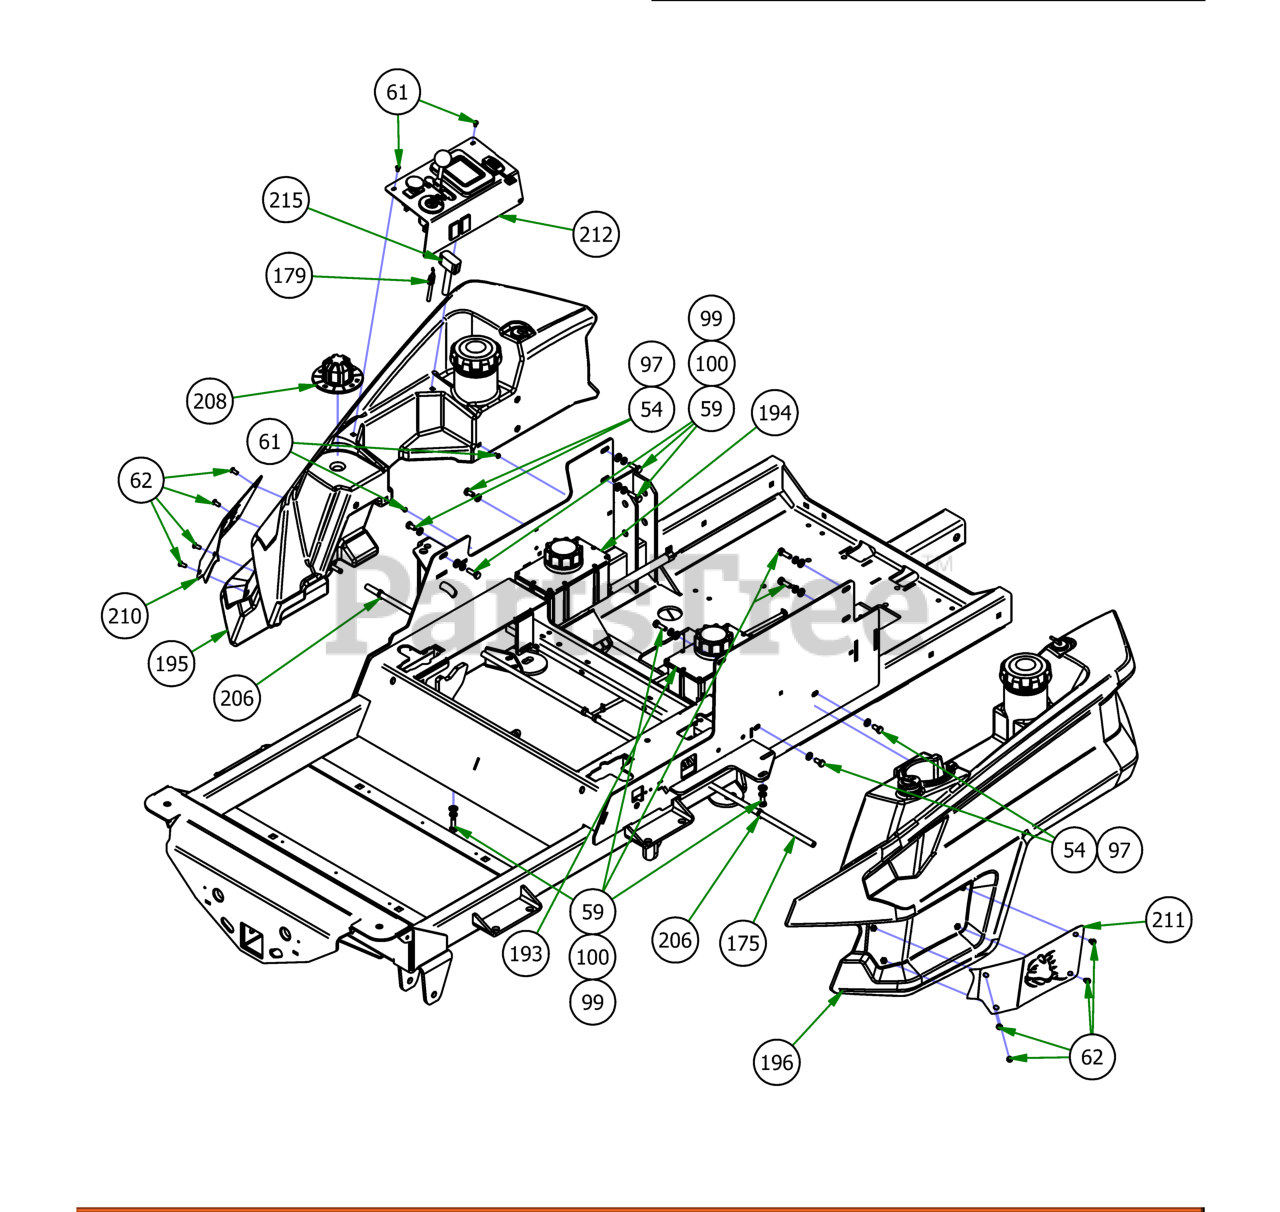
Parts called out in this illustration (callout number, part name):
54	5/16-18 x 5/8 Hex Bolt
59	5/16" x 1" Bolt
61	10-32 x 3/8" Button Socket Head Bolt
62	1/4" x 1/2" BS C/S 18-8 SS
97	1/4" Flat Washer
99	5/16" Flat Washer
100	5/16" Lock Washer
175	2019 Rebel Rogue Renegade Fuel Line for Vanguard & Yamaha
179	Outlaw Throttle Cable
193	LH Rogue Hydro Tank Assy
194	RH Rogue Hydro Tank Assy
195	2019 Right Rebel, Rogue, Renagade Fuel Tank (GAS)
196	2019 Left Rebel, Rogue, Renegade Fuel Tank (GAS)
204	2019 Renegade Gas Frame - Powdercoated
206	2 EAR CLAMP 12.5mm-15mm
208	2019 Deck Height Dial
210	2019 Outlaw Fuel Tank Insert - Right
211	2019 Outlaw Fuel Tank Insert - Left
212	Renegade Control Panel Assembly
215	2019 LCD Panel Harness-Renegade
